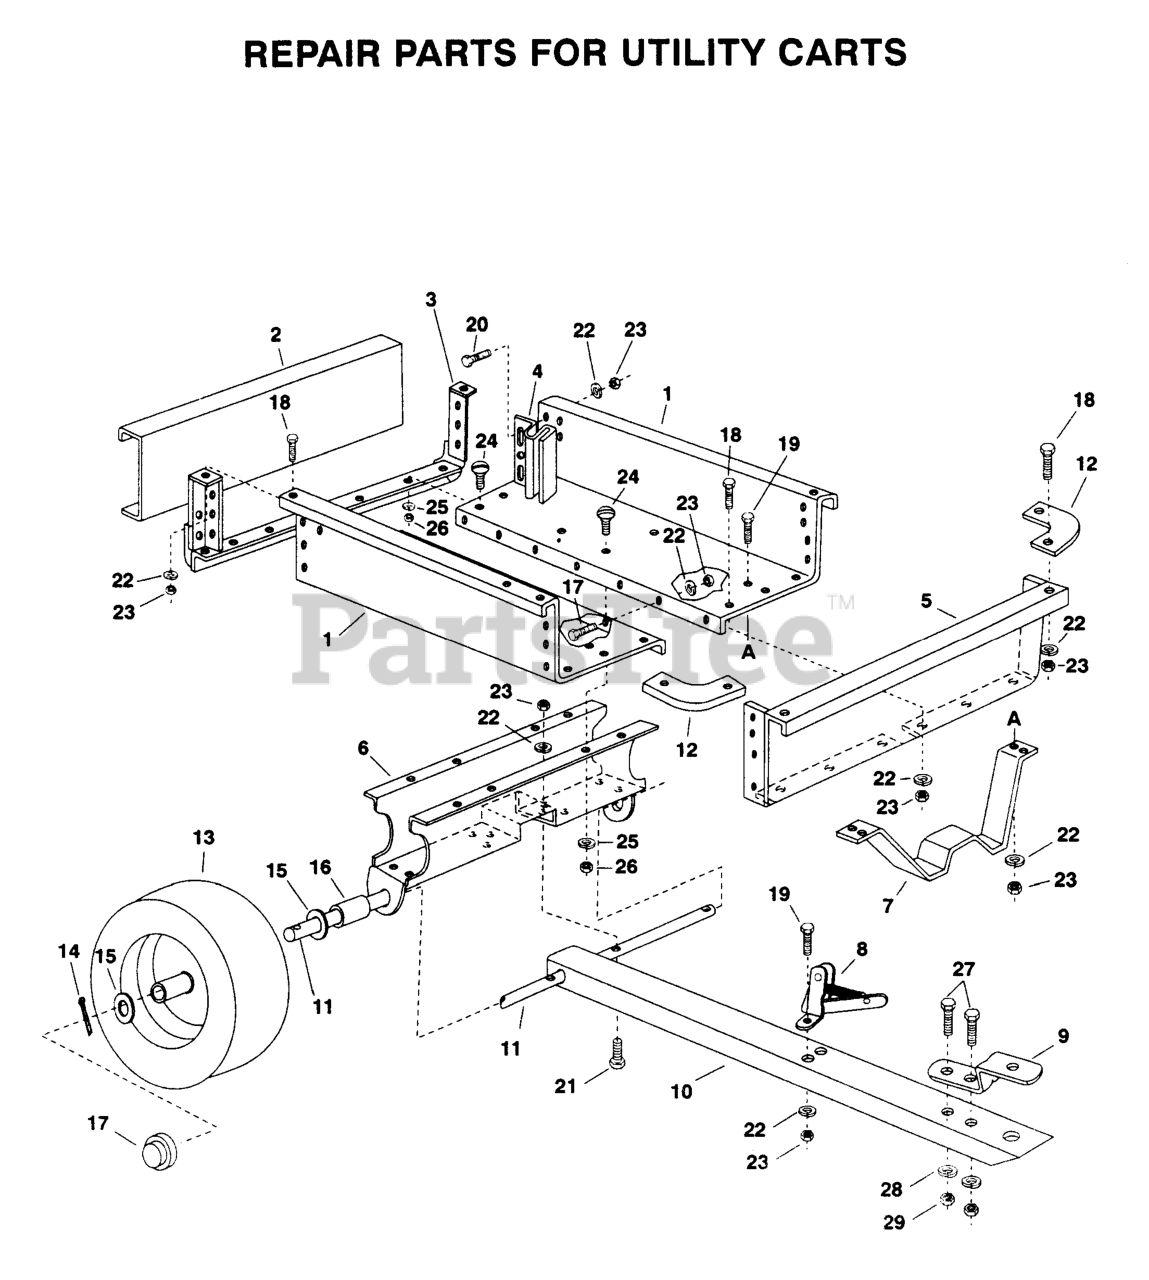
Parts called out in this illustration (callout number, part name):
2	PANEL, REAR
5	PANEL, FRONT
9	HITCH BRACKET
18	Bolt, Hex 1/4-20 x 1/2" Lg.
19	BOLT FLANGE - M6X20
20	SCREW M6S 6X20
21	Hex Head Capscrew, M6 X 1.00 X 40MM
22	SPRING WASHER
24	BOLT
28	Spring Washer
